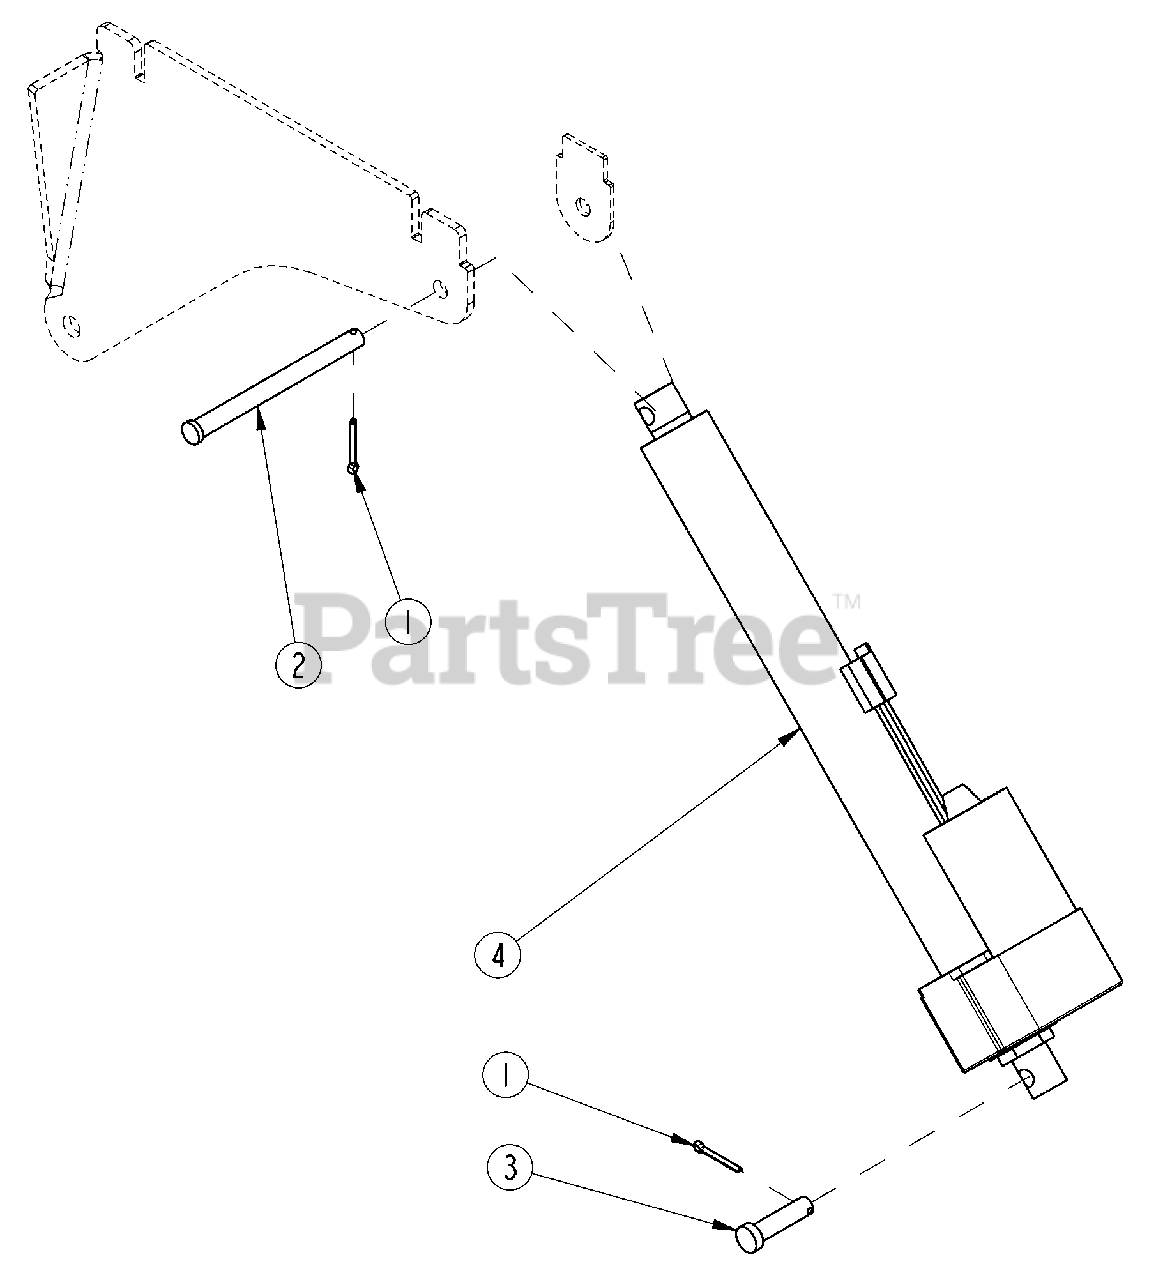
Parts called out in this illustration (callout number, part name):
1	PIN COTTER 5/32 X 1 1/4 LG
2	PIN CLEVIS 1/2 X 6
3	PIN CLEVIS 1/2X1 49/64 USABLE
4	ELECT. LINEAR ACTUATOR 12"STRK
